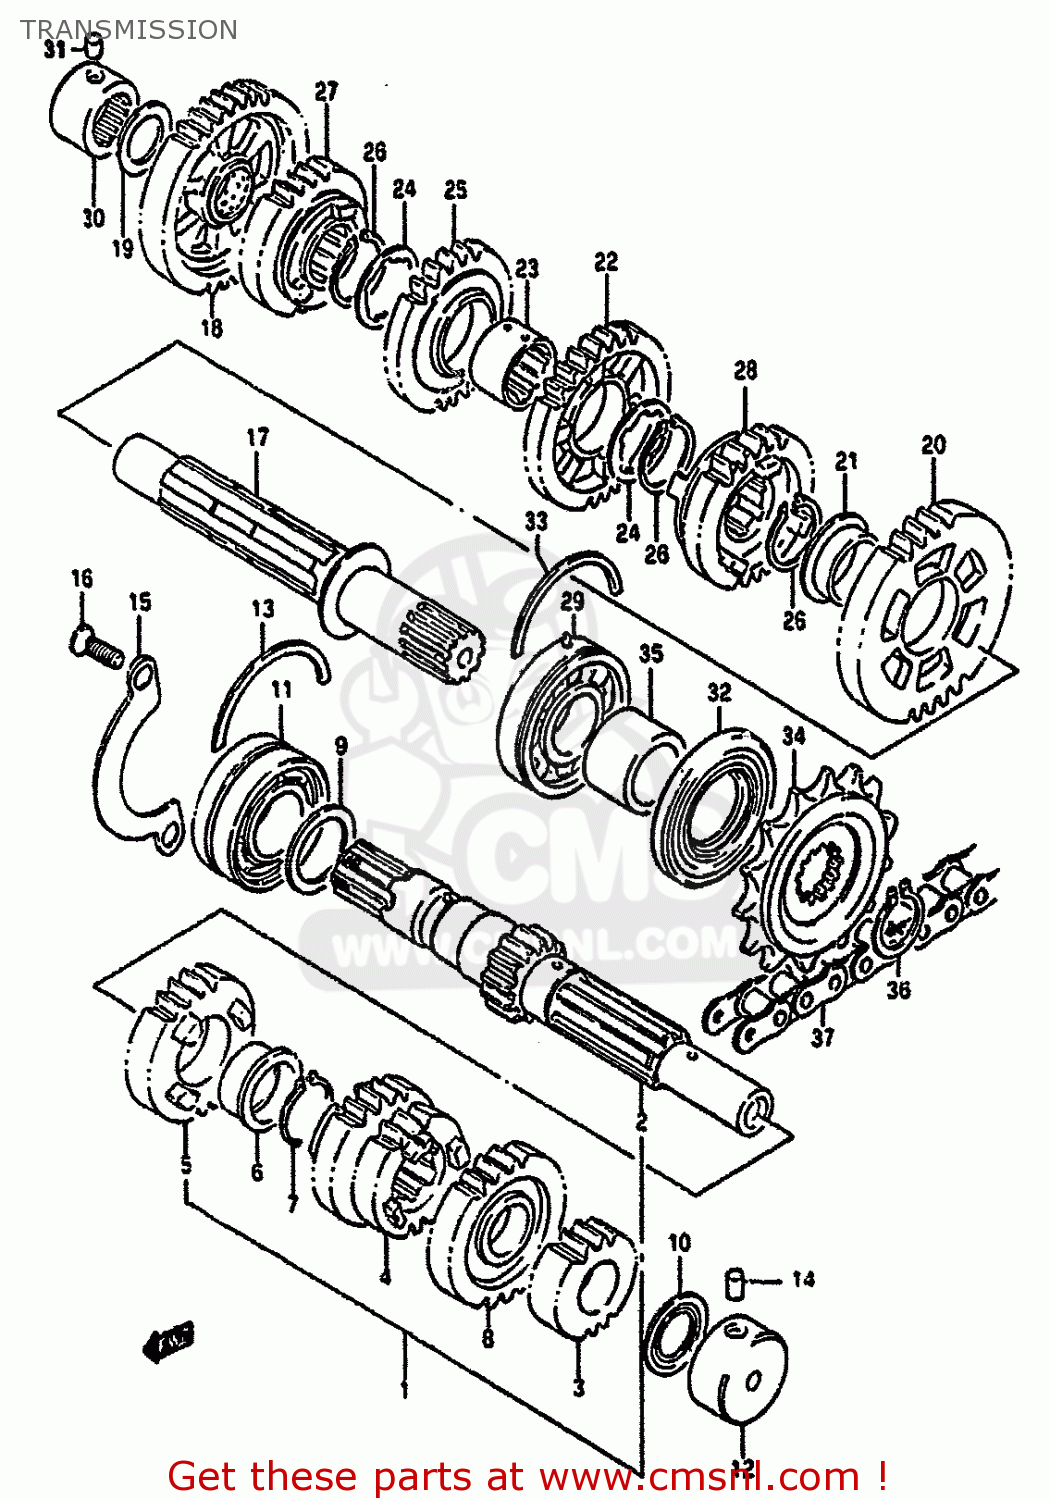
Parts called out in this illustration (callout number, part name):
1	SHAFT,COUNTER
2	COUNTER SHAFT NT:11
3	GEAR,2ND DRIVE
4	GEAR,3RD & 4TH DRIVE(NT:16/16)
5	GEAR,5TH DRIVE(NT:24)
6	BUSH
7	CIRCLIP
8	GEAR,SIXTH DRIVE
9	WASHER
10	SEAL,OIL(17X28.5X2.5)
11	BEARING(25X52X19.6)
12	BEARING(17X34X16)
13	C RING
14	PIN
15	RETAINER,CNTR SHAFT BEARING
16	SCREW
17	SHAFT,DRIVE
18	GEAR,FIRST DRIVEN
19	WASHER,THRUST
20	GEAR,2ND DRIVEN
21	BUSH
22	GEAR,3RD DRIVEN
23	SPACER,3RD DRIVEN GEAR
24	WASHER,LOCK
25	GEAR,FOURTH DRIVEN
26	RING,SNAP
27	GEAR,5TH DRIVEN(NT:30)
28	GEAR,SIXTH DRIVEN
29	BEARING
30	BEARING(20X34X20)
31	PIN
32	SEAL,OIL(30X56X6)
33	C RING
34	SPROCKET,ENGINE(NT:14)
35	SPACER(22X30X21.4)
36	CIRCLIP
37	CHAIN,DRIVE(525V9X114LE)
